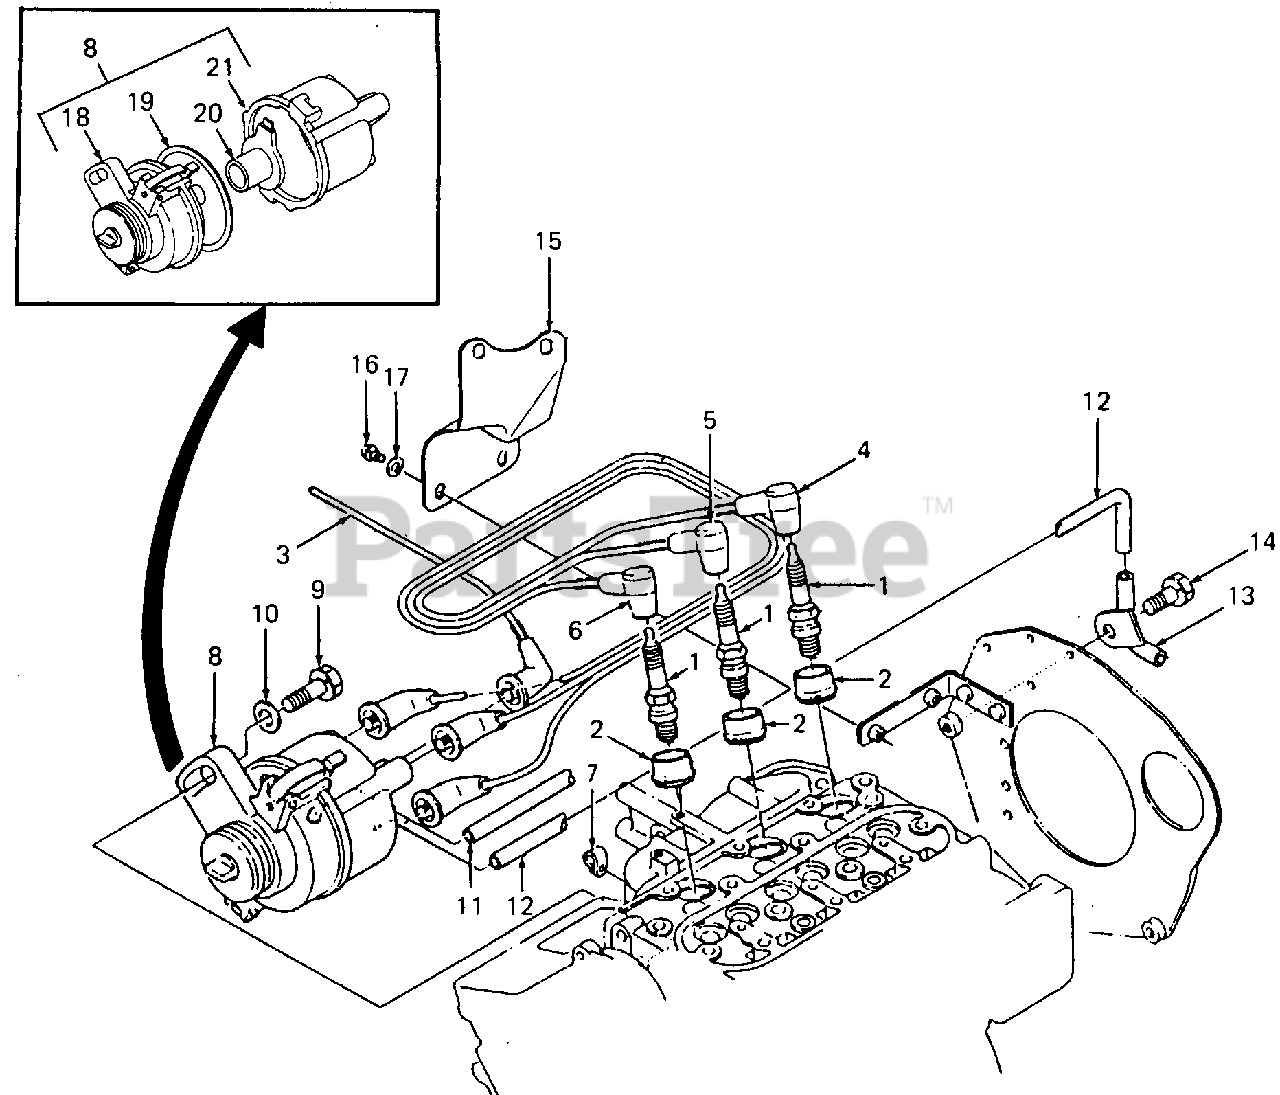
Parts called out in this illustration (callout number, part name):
1	Spark Plug
2	Cap, Spark Plug
3	Wire Assy, Center
4	Wire Assy, Plug 1
5	Wire Assy, Plug 2
6	Wire Assy, Plug 3
8	Distributor Assy
10	Washer, Plain
16	Screw w/Washer
17	Washer, Plain
